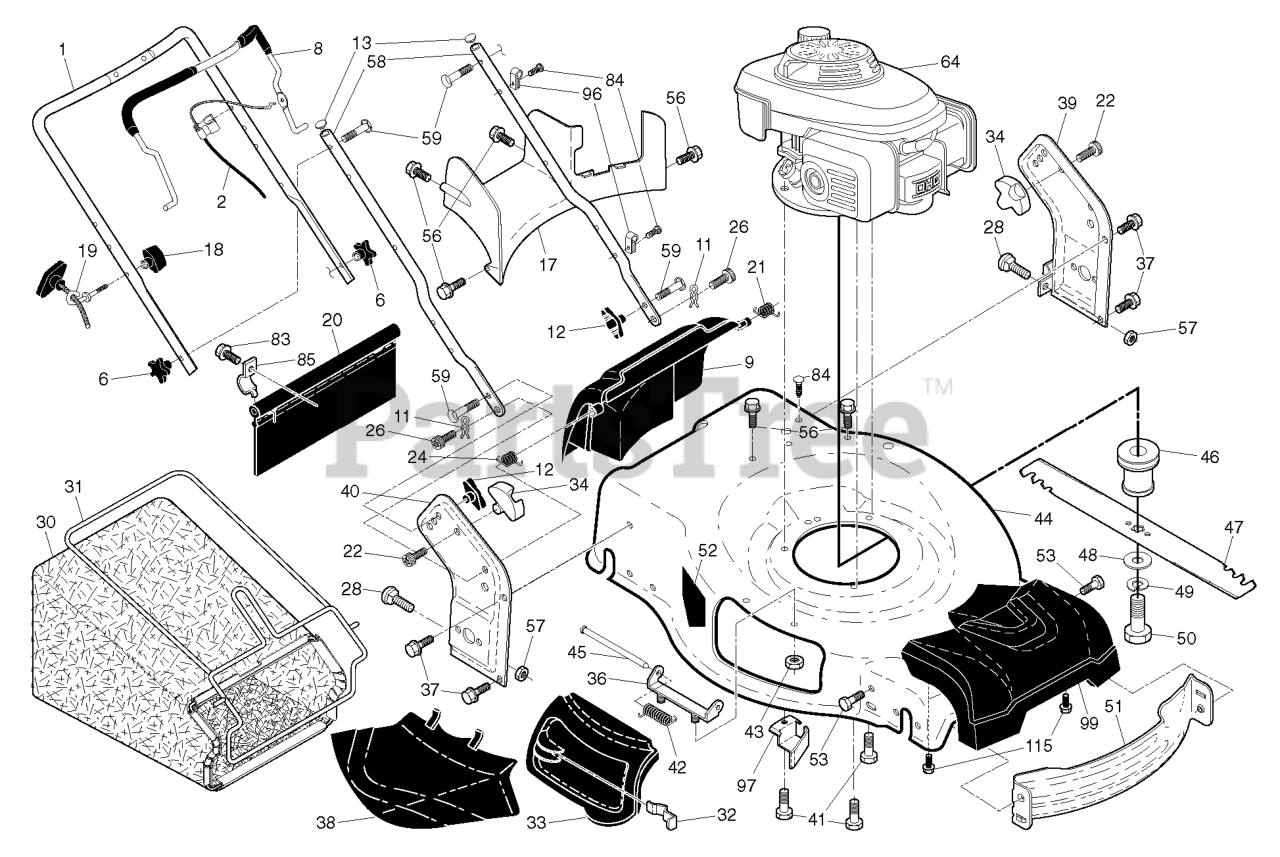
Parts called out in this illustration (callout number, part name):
1	HANDLE.UP.3POS.BS.AW2.GREY
2	CABLE.MZR.ZONE.CONTROL
6	KNOB.HANDLE.PLASTIC.STAR.BLACK
8	BAIL.OM.ERGO.BENT.MZR.ORAN.668
9	DOOR.REAR.ASM.22+GEN.FG/RG.498
11	COTTER.HAIRPIN.DOOR/HANDLE.PIV
12	KNOB, DEFLECTOR
13	PLUG.PLASTIC.7/8".14-20.GAUGE
17	BAFFLE.REAR.22+RGD.AWD.PLASTIC
18	T-KNOB.NEW ROPE GUIDE
19	GUIDE.ROPE.BLK.ZINC.CHROM
20	SKIRT.REAR.22PLUS.RGD.LW(2 2MC
21	SPRING.LH.BLACK
22	SCREW.PAN.HEAD.#10
24	SPRING.RH.GRAY
26	SCREW,DOOR/HANDLE.PIVOT
28	BOLT.CARRIAGE.LN.5/16-18X.5/8
30	GBAG.B561029ER.GRY.HUSQ.SILV
31	FRAME.GBAG.22+.BLK
32	LATCH.DOOR.ZINC
33	DOOR.MULCH.22 PLUS.HUSQ.GREY
34	BRACKET.GRASSBAG.ATTACHING.BLK
36	BRACKET.ASM.HINGE.21.FWGD.
37	BOLT.5/16HEX.WHS.HD
38	DEFLECTOR.CLIPPING.22.BLACK
39	BRACKET.ASM.HANDLE.LT.22+.GREY
40	BRACKET.ASM.HANDLE.RT.22+.GREY
41	BOLT 3/8-16X1-1/8
42	SPRING.TORSION
43	NUT.FLANGE.1-4-20-SERR
44	HOUSING.22+RGD.MCUT.WO.HUS.TRI
45	ROD.HINGE.21
46	ADAPTER.BLADE.25MM.3MPH
47	BLADE REAPER, 22 IN RUST
48	WASHER,HARDEN
49	LOCKWASHER
50	SCREW, HEX HD 3/8-24 X 1-3/8
51	BAFFLE.FRONT.22.PLUS
52	DECAL.INTERNATIONL.CUTFINGER
53	BOLT.5/16HEX.WHS.HD
56	SCREW.HX.13X.750
57	NUT.FLANGE.5/16
58	HANDLE.LOWER.22+.BT.GRAY
59	BOLT, HANDLE 5/16-18X1.75
83	TAPPING SCREW
84	FASTENER.PUSH.O.250X0.783
85	BRACKET.SKIRT.22+.BZP
96	CLIP.CABLE.BLK
97	BRACKET.BELT.GUIDE.22+.BZP
99	COVER.ASM.FRONT.HUSQ.22+RGD
115	SCREW.HI-LO. 5/16 X 1.00
